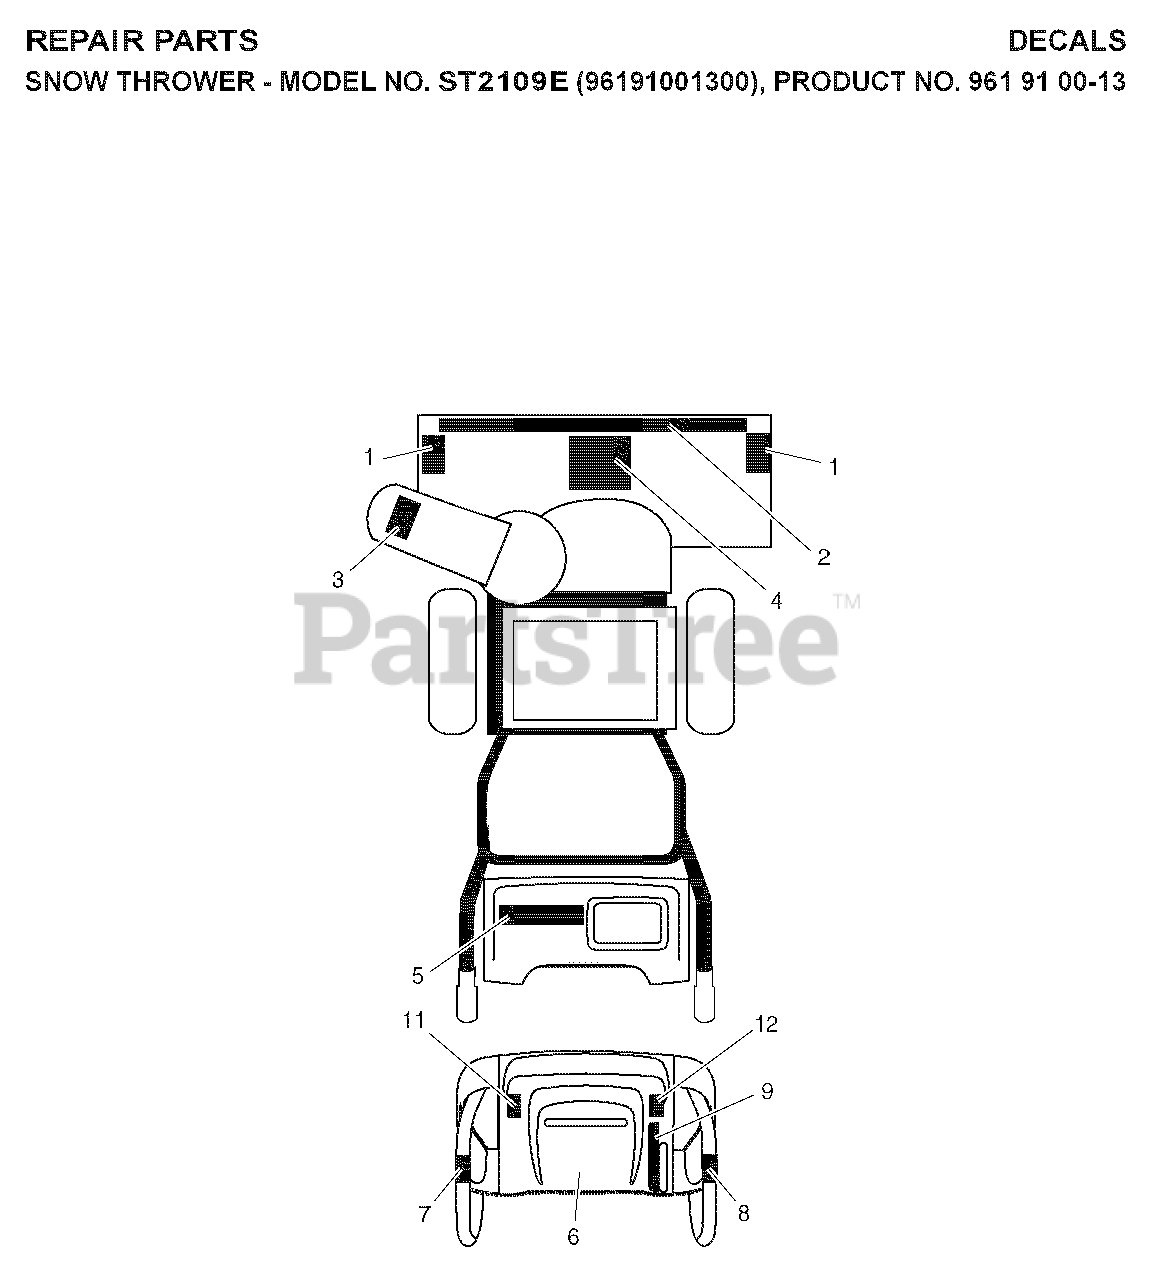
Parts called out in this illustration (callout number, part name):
1	DECAL.AUGER.SAFETY.
3	DECAL.CHUTE.SAFETY.
4	DECAL.AUGER."
6	DECAL.CONSOLE.INSTRUCTION
10	DECAL.REM.DEFLECTOR.LT
11	DECAL, LH TRIGGER
12	DECAL, RH TRIGGER
